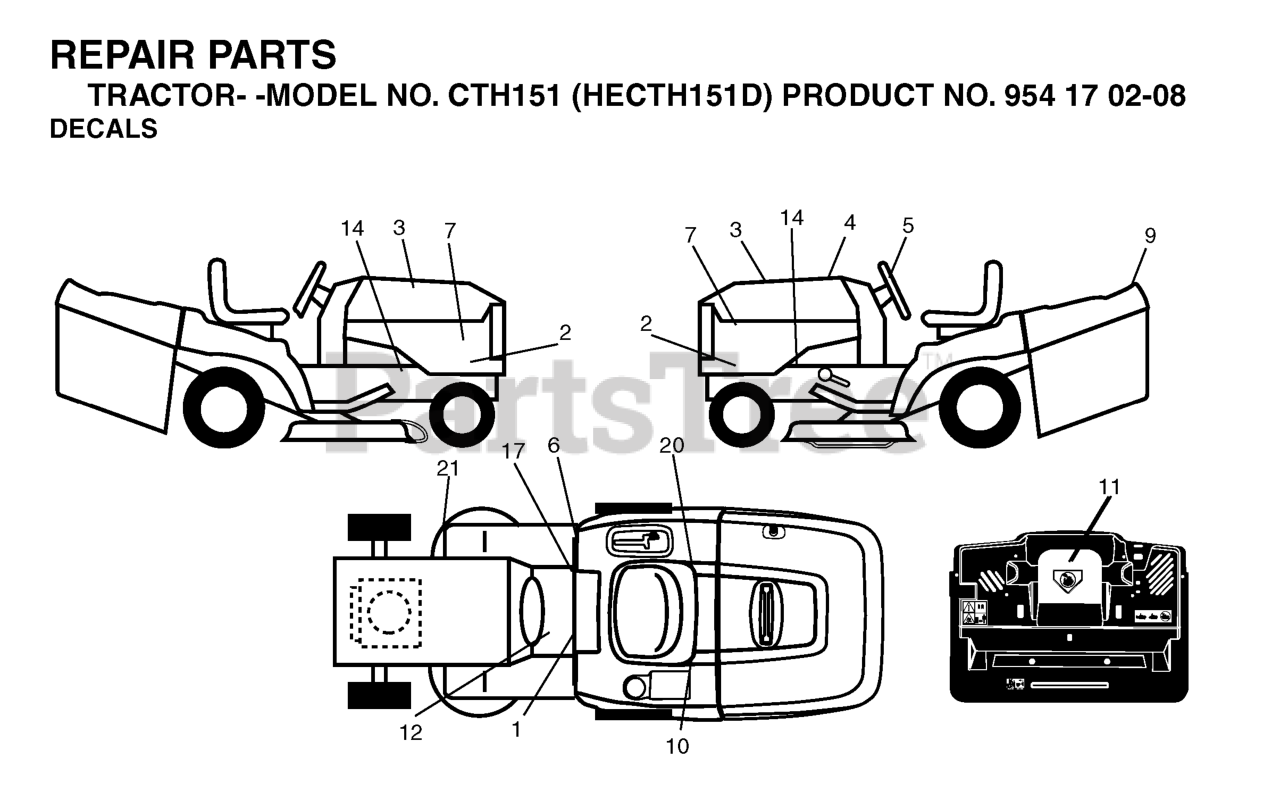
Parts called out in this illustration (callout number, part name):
1	DECAL READ OWNER'S MAN SYMS
5	DECAL.STEERING.HUSQ.BLUE
6	Decal, Fender 100 DB/CE
7	DECAL.HOOD.HUSQVARNA.INTERNATI
10	DECAL BTRY SYMBOLS
11	DECAL.INTERNATIONL.CUTFINGER
12	DECAL
17	DECAL PARK BRAKE
20	DECAL.BYPASS.FENDER.CRD.LT.YT
